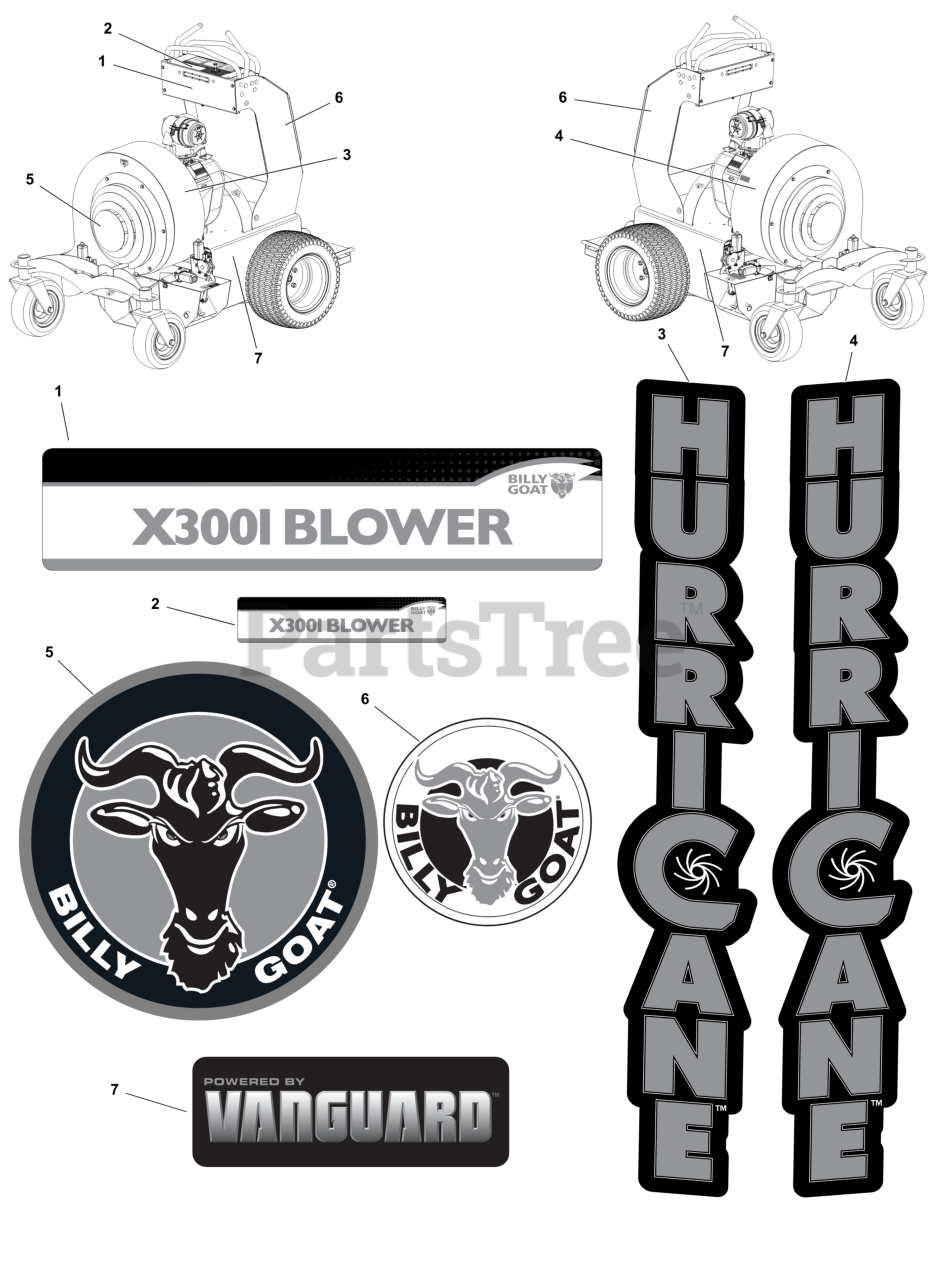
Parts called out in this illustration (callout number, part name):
1	DECAL, X3001 BADGE, BG
2	DECAL, X3001 TOP PANEL, BG
3	DECAL, X3000 HURRICANE_VERT, LH
4	DECAL, X3000 HURRICANE_VERT, RH
5	DECAL, X3000 FRONT LOGO
6	LABEL, PRODUCT DECAL LG CIRCLE
7	DECAL, BRAND
